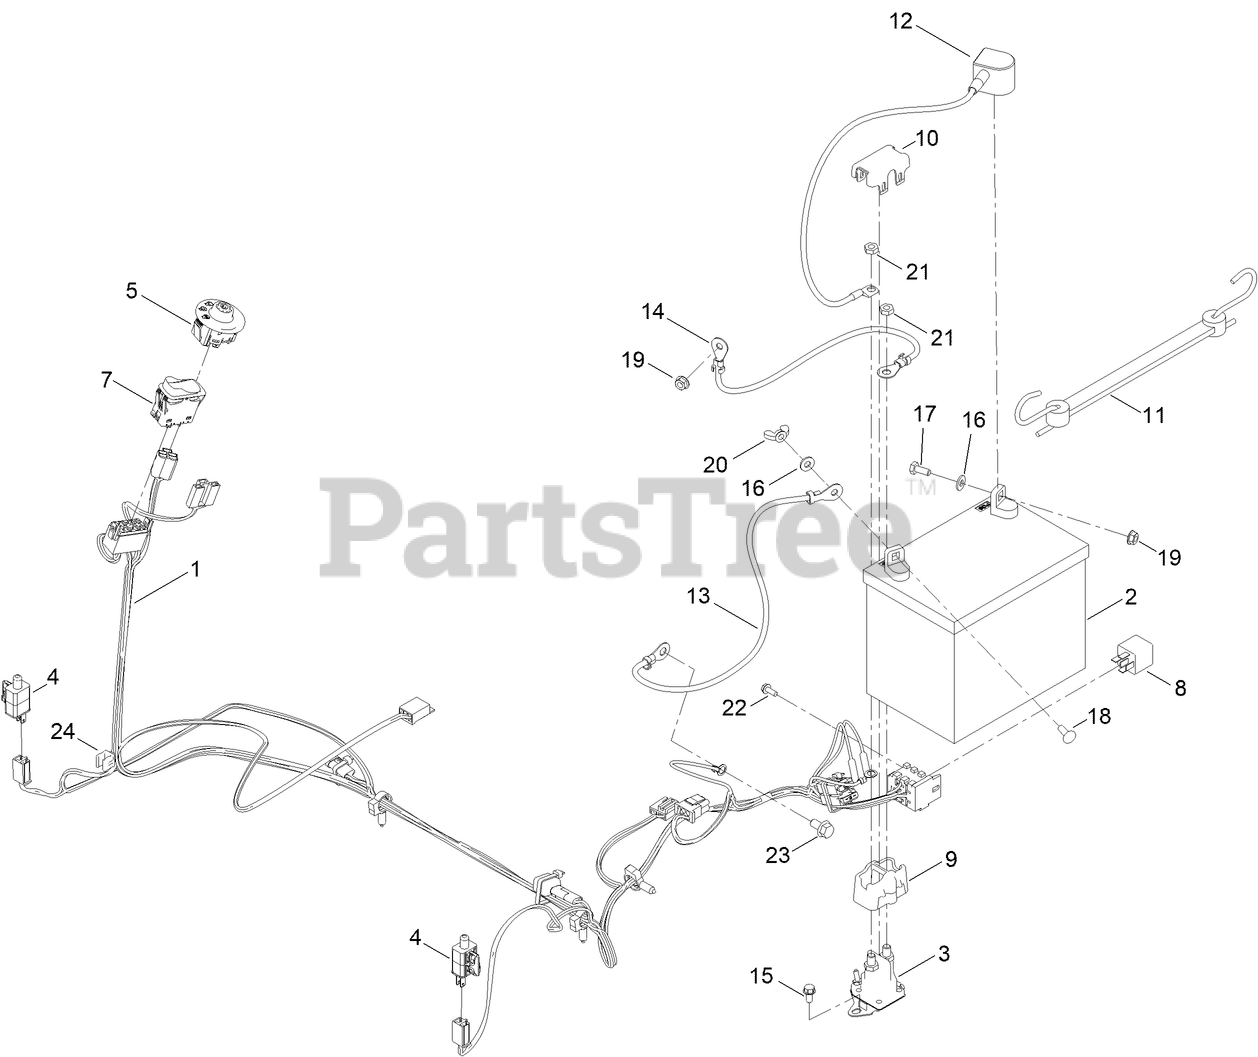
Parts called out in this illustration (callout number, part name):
1	HARNESS-WIRE, MAIN
3	SOLENOID
4	SWITCH
5	SWITCH-IGNITION
7	SWITCH-ROCKER, ON-NONE-ON
9	COVER-SOLENOID
10	CAP-SOLENOID
11	HOLDDOWN-BATTERY
12	CABLE-BATTERY,RED
13	CABLE-BATTERY, BLACK
14	CABLE-BATTERY, POSITIVE
15	SCREW-HWH
16	WASHER-FLAT
17	SCREW-HH
18	BOLT-CARR
19	NUT-HF
20	NUT-WING
21	NUT-JAM
22	SCREW-TAPTITE
23	SCREW-HHF
24	CLIP-EDGE W/TIE, PERPENDICULAR
